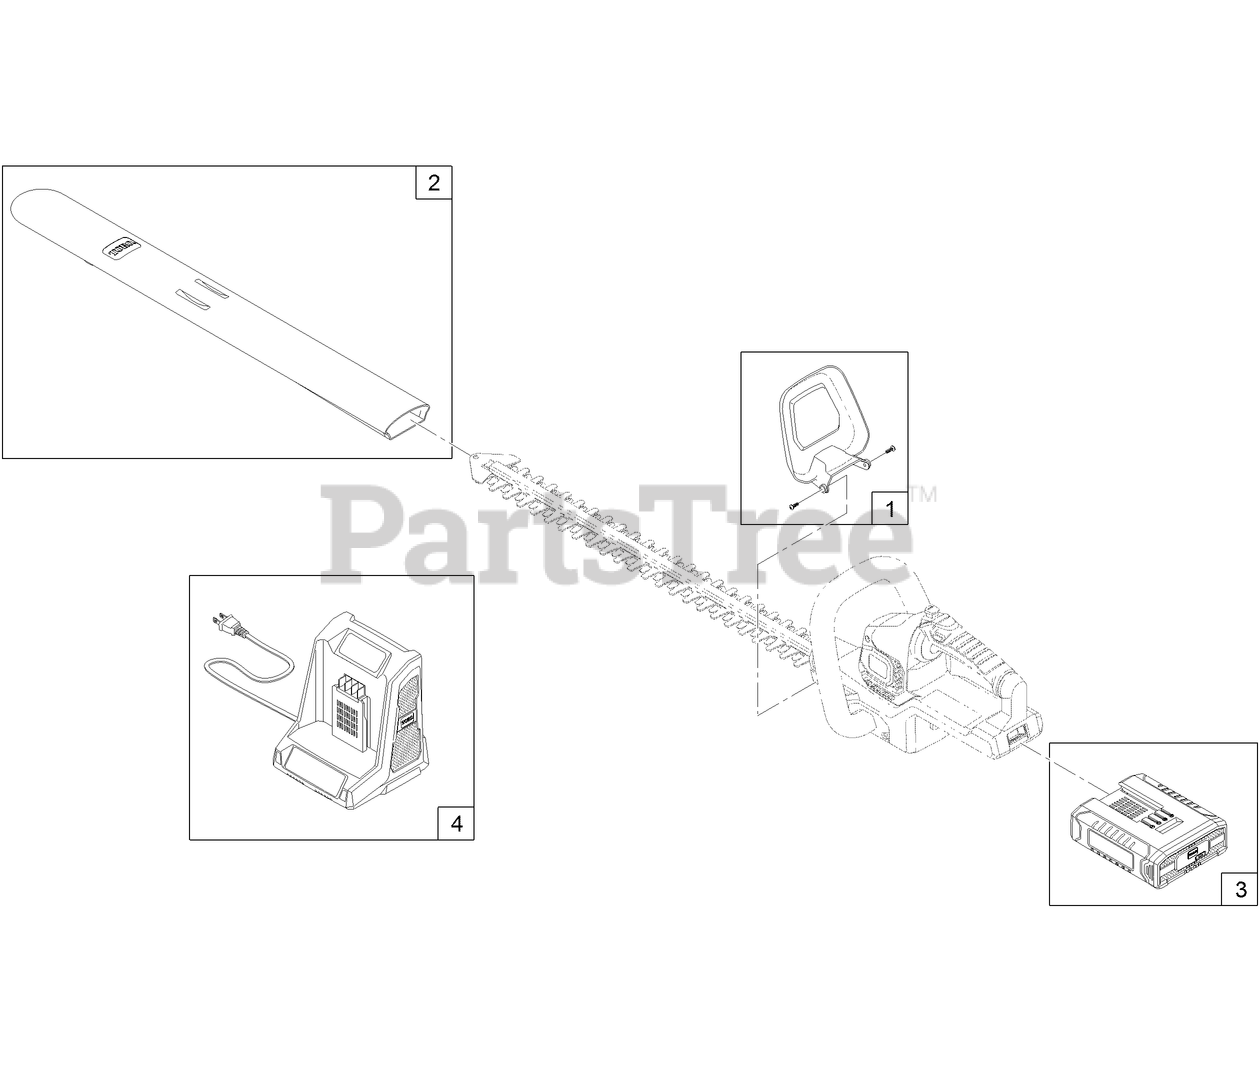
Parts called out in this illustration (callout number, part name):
1	GUARD-TRIMMER, HEDGE
2	SLEEVE-BLADE, HEDGE TRIMMER
3	BATTERY-40V MAX
4	CHARGER-40V MAX
